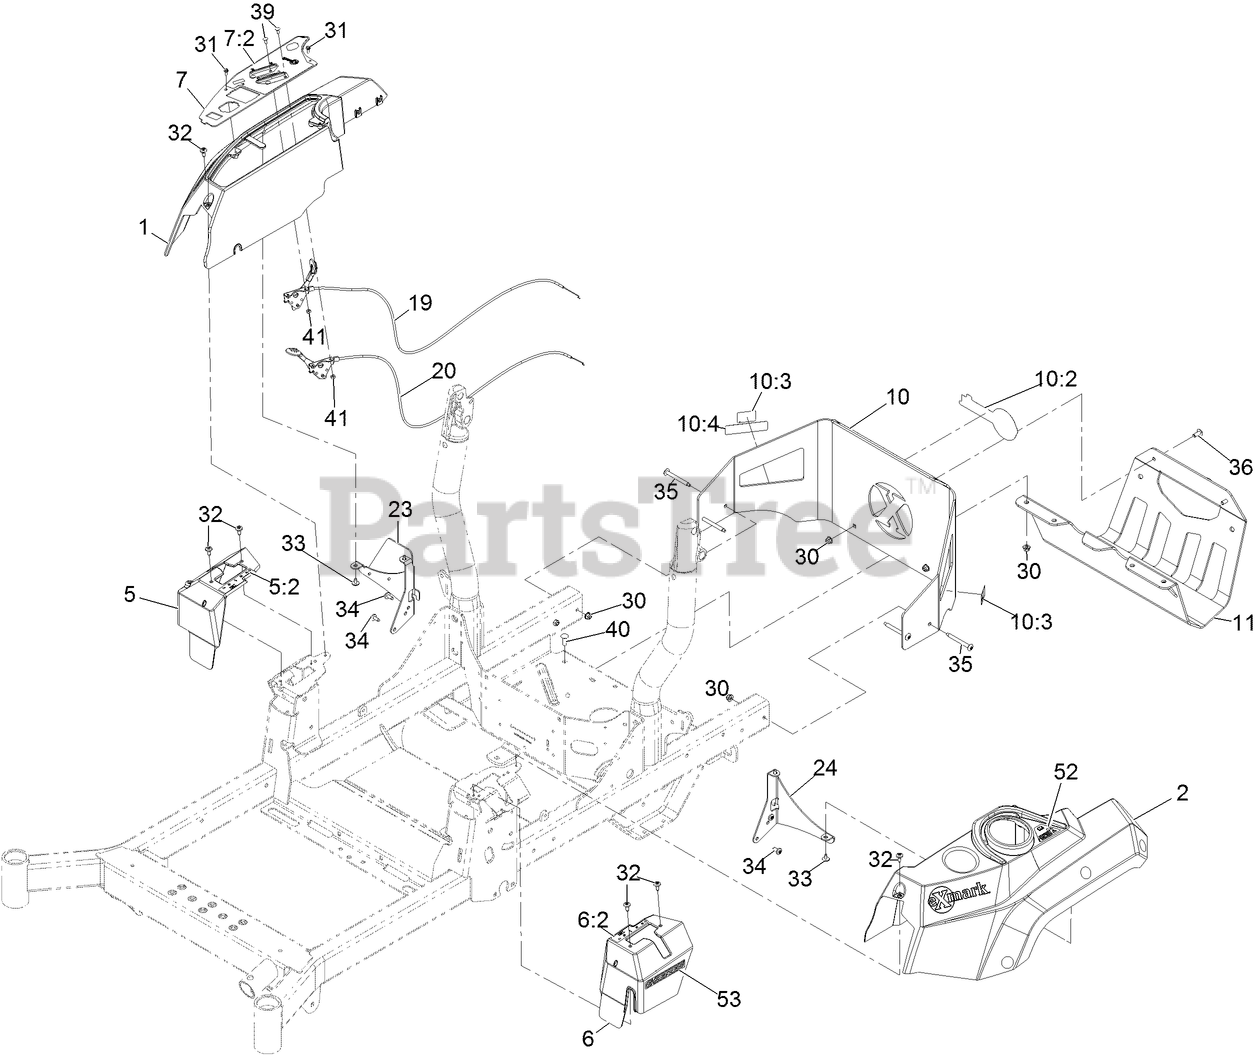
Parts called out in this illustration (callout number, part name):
1	CONSOLE, RH
2	CONSOLE, LH
5	COVER-CONTROL, MOTION (RH
5:2	Decal-Control, Motion (RH)
6	COVER-CONTROL, MOTION (LH
6:2	Decal-Control, Motion (LH)
7	ASM-CONTROL PANEL W/EXMARK DECAL
7:2	DECAL-CONTROL PANEL
10	REAR GUARD ASM
10:2	DECAL, EXMARK LOGO
10:3	DECAL-WARNING
10:4	DECAL-ARRESTOR, SPARK
11	GUARD-MUFFLER
19	CABLE-CONTROL, CHOKE
20	CABLE-CONTROL, THROTTLE
23	SUPPORT-CONSOLE, RH
24	BRACKET-CONSOLE, LH
30	NUT-HF, NI
31	SCREW-HWH
32	SCREW-SHOULDER
33	SCREW-TORX
34	SCREW-TORX
35	SCREW-TORX
36	SCREW-TORX
39	BOLT-CARR
40	SCREW-CARR
41	NUT-LOCK, NI
52	DECAL-FILL, FUEL
53	DECAL-E-SERIES
